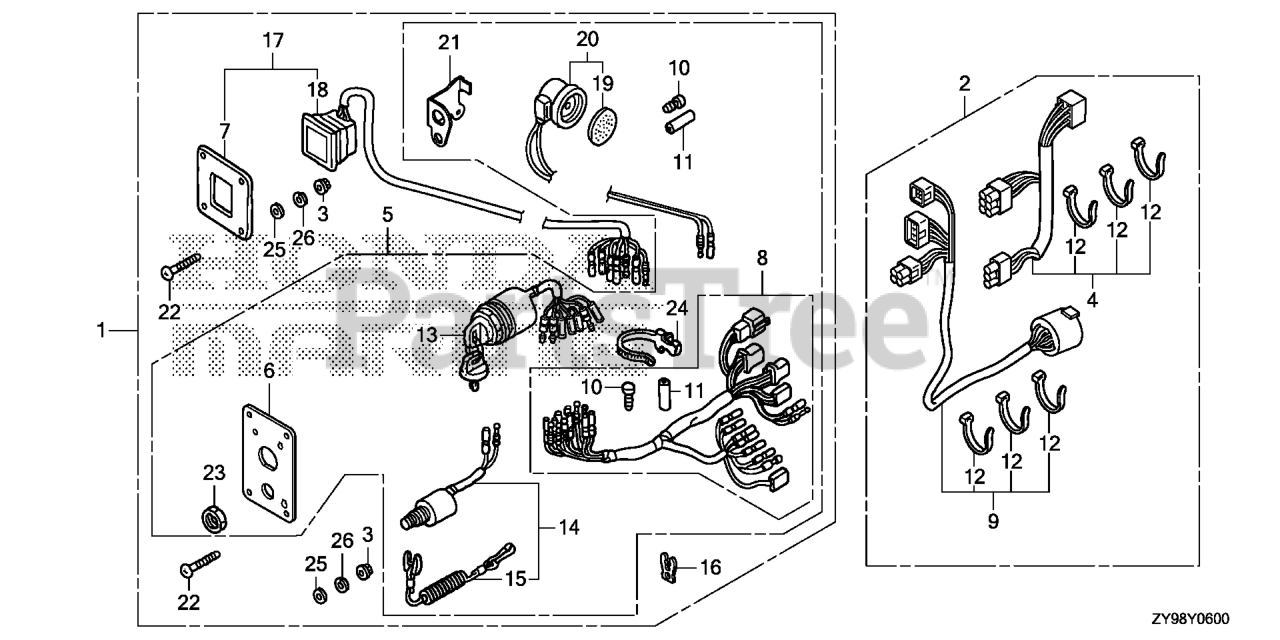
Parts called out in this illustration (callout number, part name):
1	PANEL KIT, SWITCH (4-LED) (B)
2	CABLE SET, PANEL INDICATOR (20FT)
2	CABLE SET, PANEL INDICATOR (25FT)
2	CABLE SET, PANEL INDICATOR (30FT)
3	NUT, FLANGE (5MM) DUAL QTY = (8) (SINGLE)
4	WIRE ASSY., INDICATOR (20FT)
4	WIRE ASSY., INDICATOR (25FT)
4	WIRE ASSY., INDICATOR (30FT)
5	PANEL ASSY., SWITCH
6	PANEL, CONTROL
7	PANEL, CONTROL
8	HARNESS ASSY., SWITCH PANEL
9	CABLE ASSY., SWITCH PANEL (20FT) (NHK MEC)
9	CABLE ASSY., SWITCH PANEL (25FT) (NHK MEC)
9	CABLE ASSY., SWITCH PANEL (30FT) (NHK MEC)
10	PLUG, CONNECTOR (INNER) (TROLLING CONTROL)
11	PLUG, CONNECTOR (OUTER) (ENGINE NO.)
12	TIE, CABLE (NATURAL 2.4X92) Use up to Frame SN 1300359.
13	SWITCH ASSY., COMBINATION (SINGLE) (DUAL)
14	SWITCH ASSY., EMERGENCY STOP
15	WIRE, EMERGENCY (SINGLE) (DUAL)
16	CLIP, EMERGENCY LOCK
17	PANEL ASSY., INDICATOR (4-LED)
18	LAMP ASSY., INDICATION (4-LED)
19	PLATE, TURN SIGNAL BUZZER DUAL QTY = (2) (SINGLE)
20	BUZZER, WARNING DUAL QTY = (2) (SINGLE)
21	BRACKET, BUZZER
22	SCREW, PAN (5X40) DUAL QTY = (8) (SINGLE)
23	NUT, HEX. (16MM) DUAL QTY = (2) (SINGLE)
24	BAND, WIRE HARNESS (150MM) (NATURAL) DUAL QTY = (2) (SINGLE)
25	WASHER, PLAIN (5MM) DUAL QTY = (8) (SINGLE)
26	WASHER, SPRING (5MM) DUAL QTY = (8) (SINGLE)
